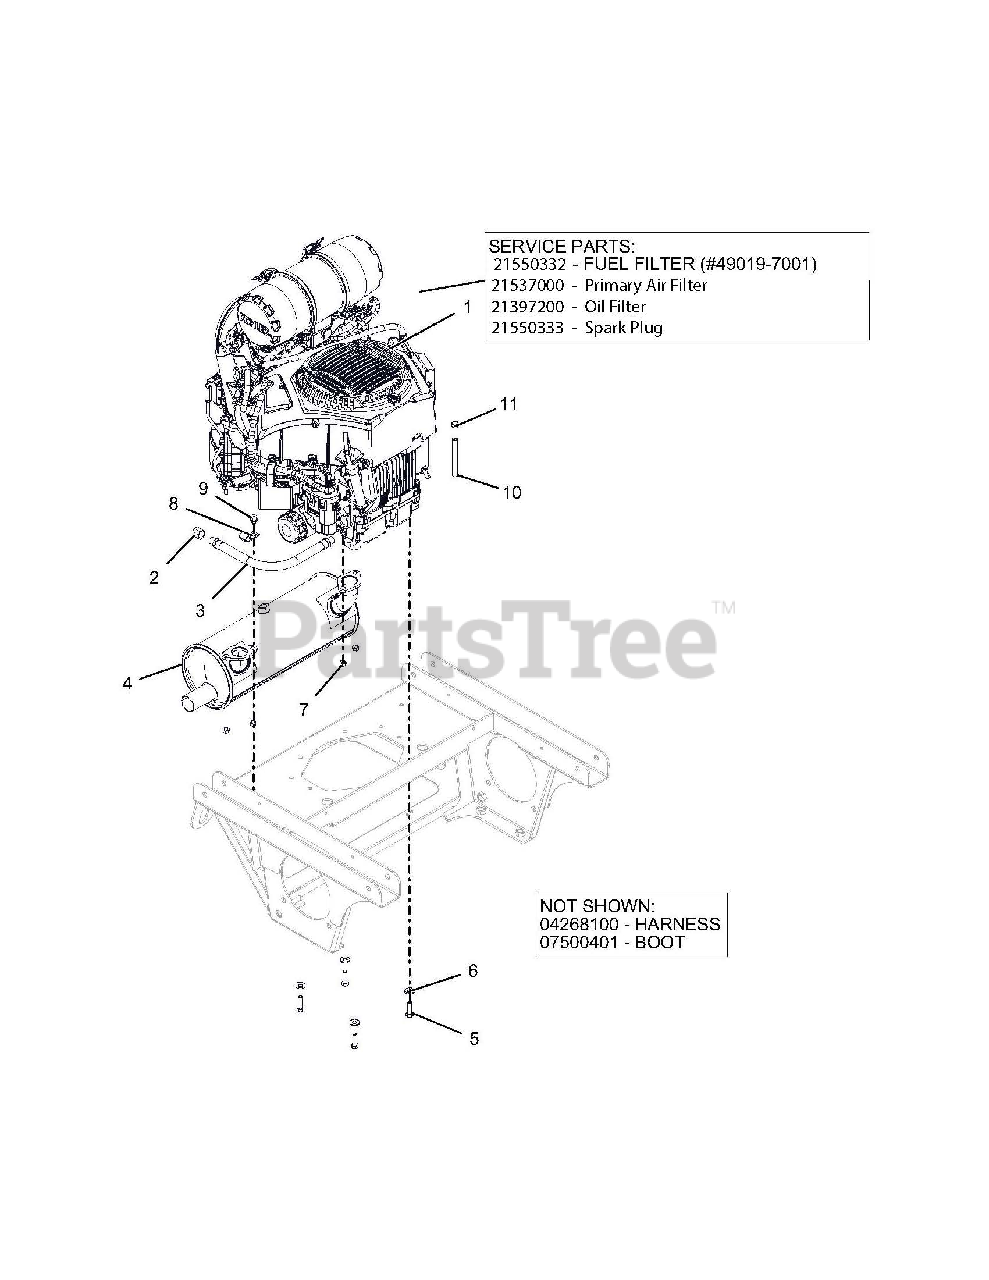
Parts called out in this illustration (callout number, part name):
1	ENGINE, KOHLER EFI
1	FUEL FILTER - #49019-7001
1	PARIMARY AIR FILTER
1	OIL FILTER
1	SPARK PLUG
2	PIPE, CAP 3/8 NPT FEMALE
3	HOSE, HYD .38-11-OK M6N0-M6N0
4	MUFFLER, KOHLER EFI
5	BLT-HEX .38-16X1.25 GR5 YWZC NYTORQ
6	WSHR, 3/8" SPRING DISC
7	NUT-LK-TOP M8-1.25 YWZC
9	SCR-TAP .38-16X.50 HWH TR YWZ
10	.25 LOW-PERM GAS HOSE 19.0" LG - VALVE TO ENGINE
11	CLAMP, FUEL LINE
